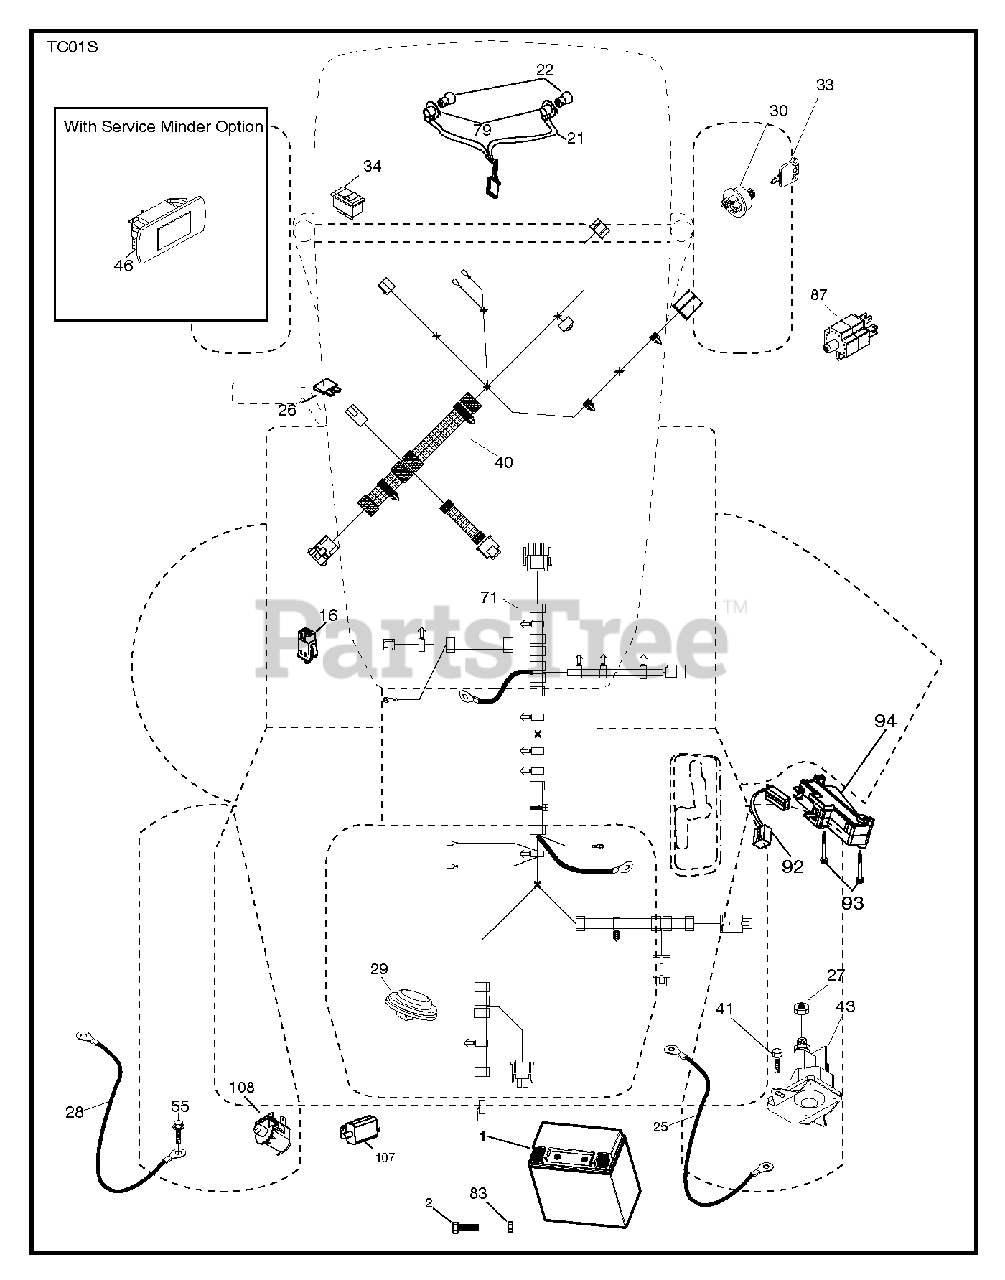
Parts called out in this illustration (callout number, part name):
16	SWITCH INTERLOOK PUSH-IN
21	HARNESS.LIGHT W/4152J BULBS
22	LIGHTBULB
26	FUSE 20AMP
27	NUT
29	SWITCH.SEAT.DELTA.OPC.
30	SWITCH.IGN.DELTA.W.LGH.ROS
33	KEY.CHAIN.BLISTER.PACK.GEN.INT
34	SWITCH LT
41	SCREW
43	SOLENOID.W/BRASS.PLUNG
55	SCREW 5/16"
79	BULB HOLDER ASM.
92	HARNESS.PIGTAIL.CONSLE
93	SCREW.PLASTITE
94	MODULE.REVERSE.ROS
108	SWITCH.SNAPMOUNT.NC
